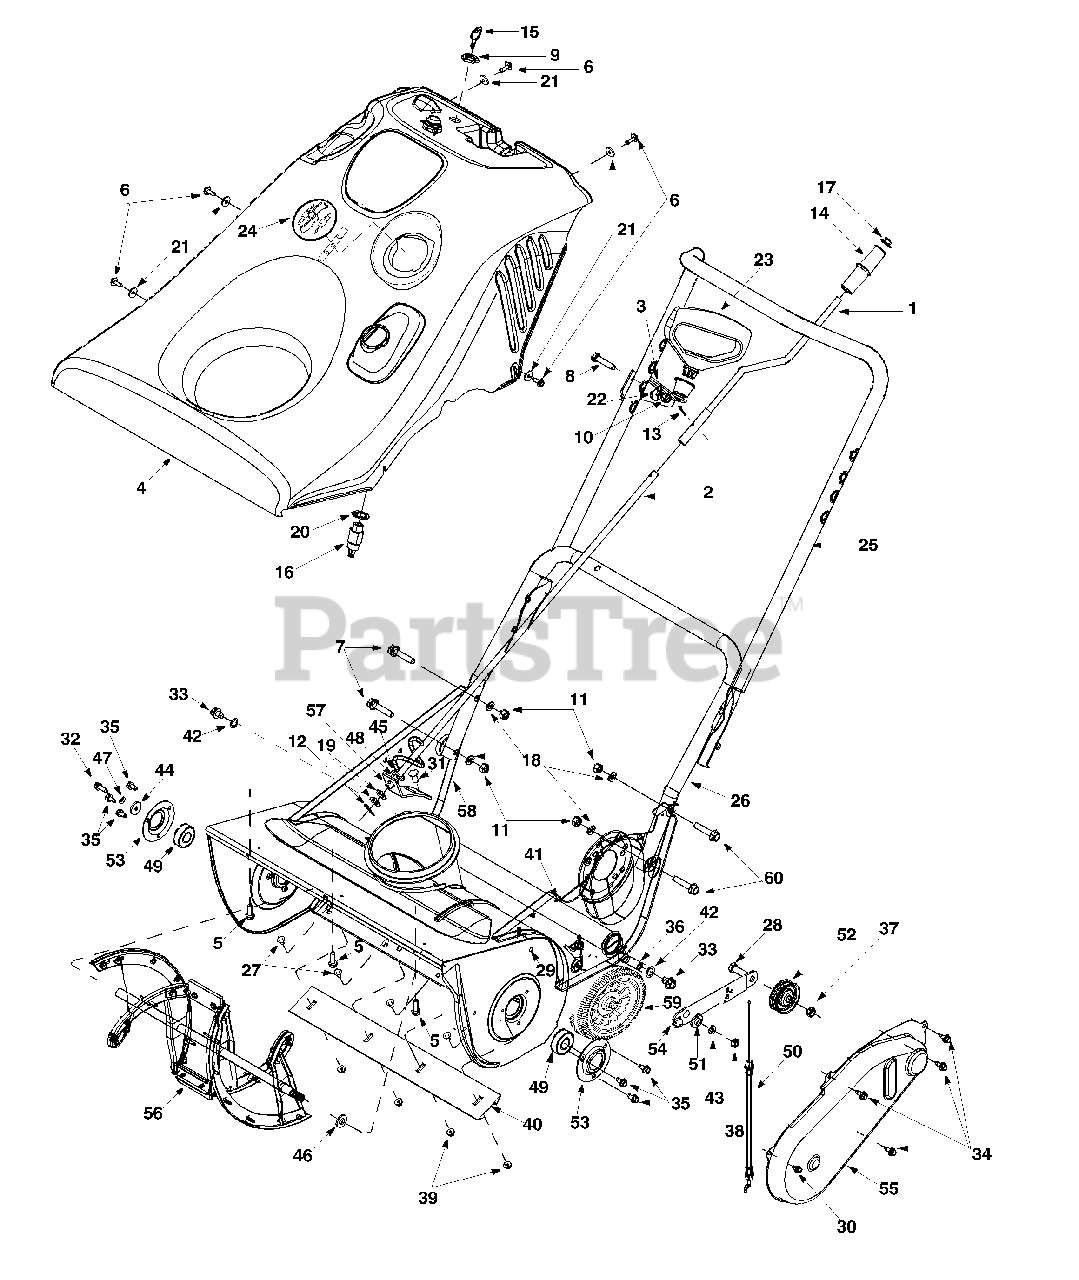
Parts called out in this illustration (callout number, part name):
3	Bracket Assembly: Mitten Grip
4	Shroud (Model 521)
5	TT Screw 1/4-15 x 0.75"
6	B Screw #10-16 x 0.625"
7	Hex Fl. Screw 5/16-18 x 1.5"
8	Hex Bolt 5/16-18 x 1.375"
11	Hex Nut 5/16-18
12	Cotter Pin
13	Cotter Pin
14	Knob: Chute Crank
15	Ignition Key
16	Switch: Electric Start Key
18	Lock Washer
19	Flat Washer
20	Internal Lock Washer
21	Flat Washer
22	Saddle Washer
23	Mitten Grip Handle
24	Spark Plug Access
29	Machine Screw
30	B Screw 1/4-14 x 0.375"
31	Carriage Bolt
32	TT Screw 1/4-20 x 0.75"
33	TT Screw 3/8-16 x 0.5"
34	AB Screw 1/4-14 x 0.625"
35	B Screw 1/4-14 x 0.5"
36	Axle Tube
37	Jam Lock Nut
38	Hex Nut 5/16-18
39	Lock Nut
40	Shave Plate
41	Extension Spring
42	Flat Washer
43	Lock Washer
44	Flat Washer
45	Beleville Washer
46	Flat Washer
47	Lock Washer
48	Plastic Bushing
49	Ball Bearing
50	Clutch Cable
51	Shoulder Spacer
52	Flat Idler
60	Hex Fl. Screw 5/16-18 x 1.25"
